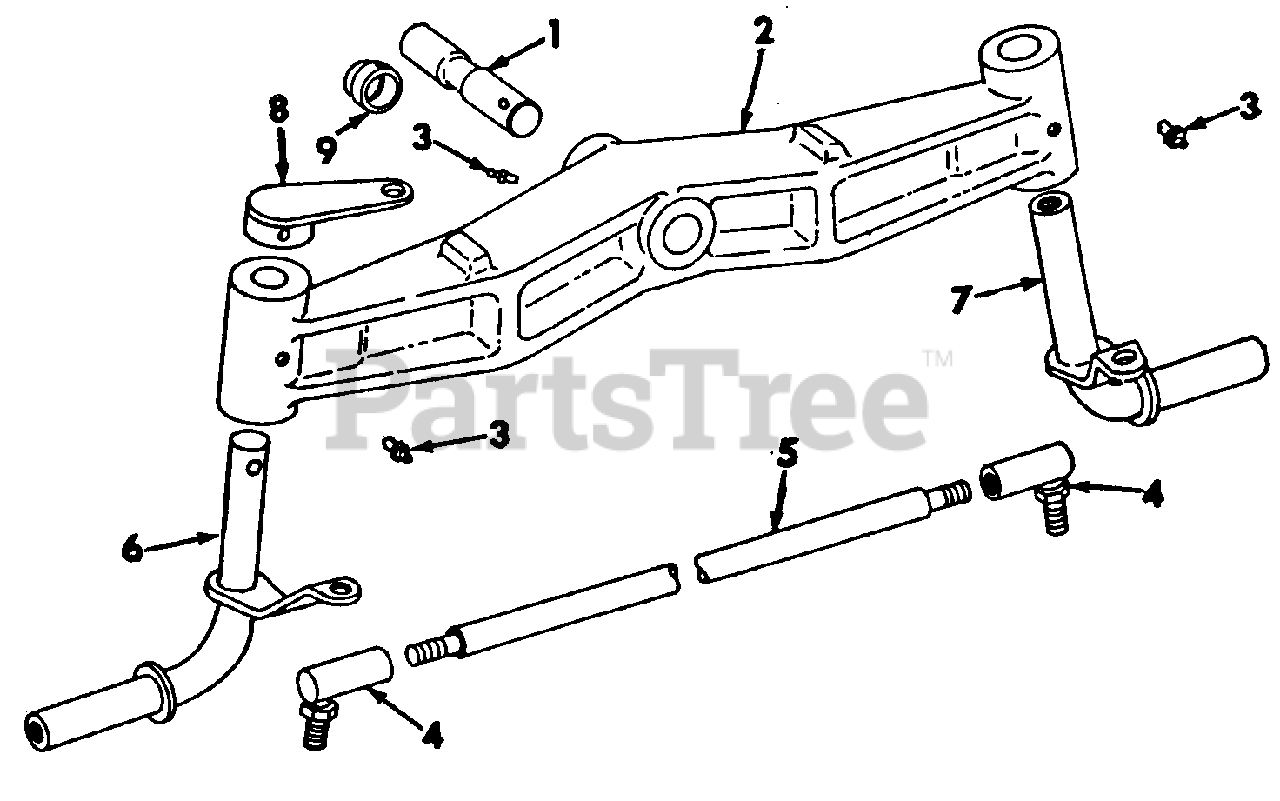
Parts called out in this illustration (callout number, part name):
1	Pin, Front Axle Pivot
2	Axle, Front
3	Fitting, 3/16 Drive Type Str Lube
4	Joint Assy, Ball
8	Arm Assy, Drag Link
9	Bushing, Front Axle Pivot Pin Front
